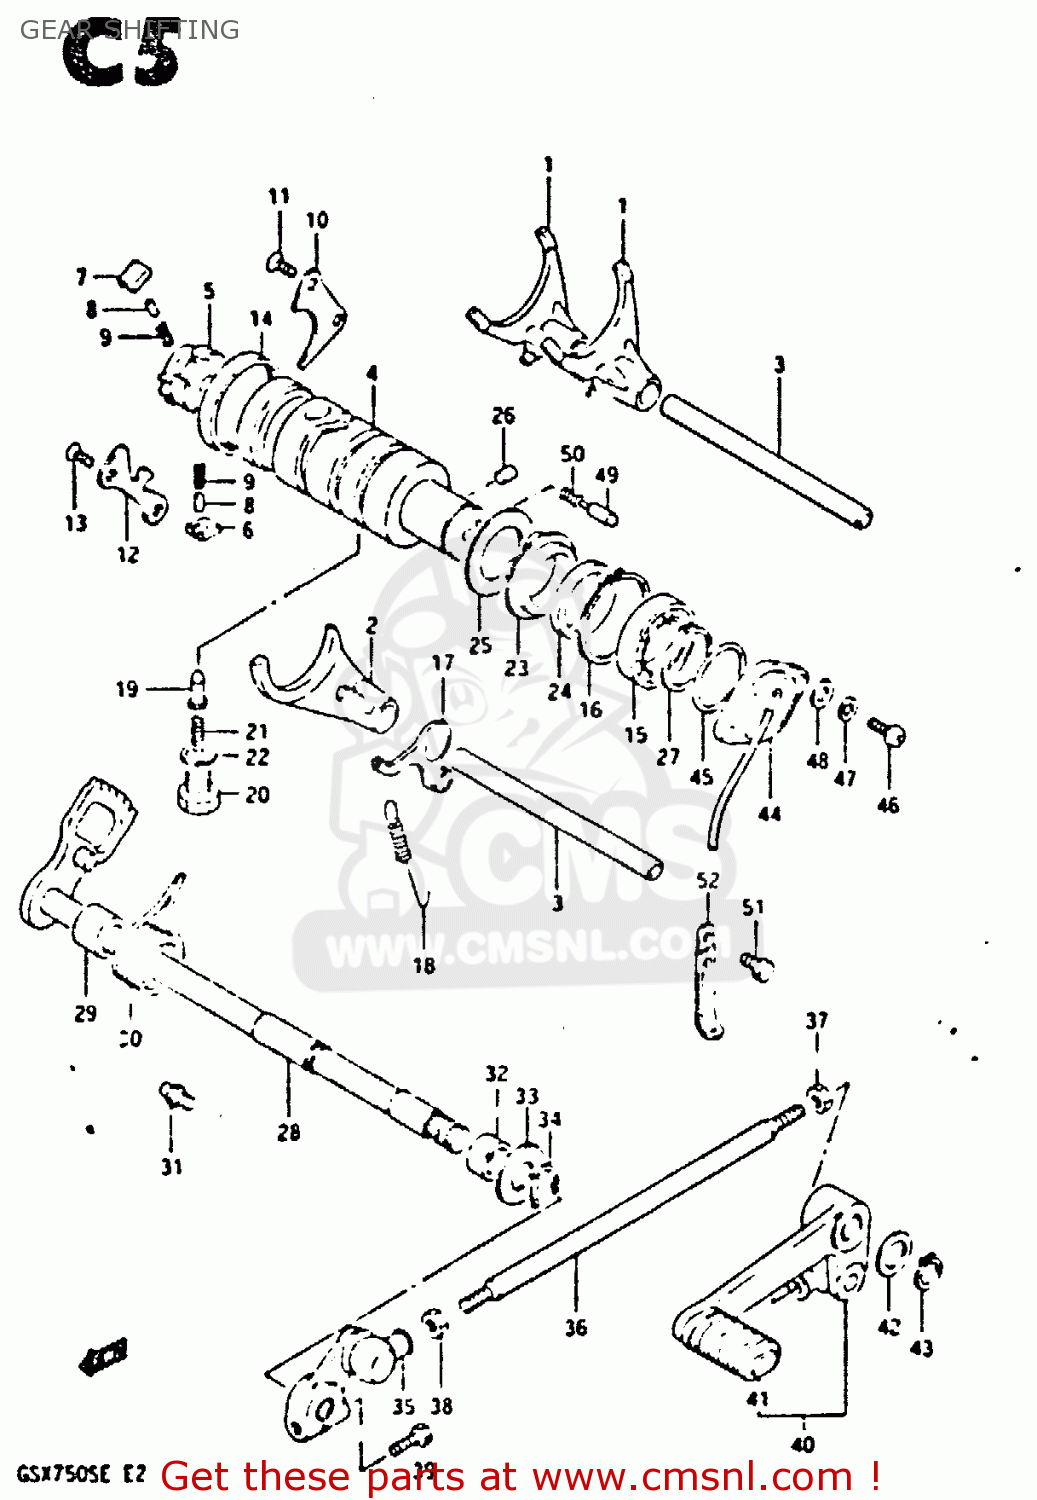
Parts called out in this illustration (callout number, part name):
1	FORK,GEAR SHIFT NO.1
2	FORK,GEAR SHIFT NO.2
3	SHAFT,GEAR SHIFT FORK
4	CAM,GEAR SHIFT
5	GEAR,GEARSHIFT CAM DRIVE
6	PAWL,GEAR SHIFT NO.1
7	PAWL,GEAR SHIFT NO.2
8	PIN(5X8)
9	SPRING
10	LIFTER,GEAR SHIFT PAWL
11	SCREW
12	GUIDE,GEAR SHIFT CAM
13	SCREW
14	BEARING(43X49X12)
15	BALL BEARING
16	CIRCLIP,42MM
17	STOPPER,GEAR SHIFTING
18	SPRING
19	STOPPER,GEAR SHIFTING
20	HOLDER,GEAR SHIFT CAM STOP SPR
21	SPRING
22	GASKET(14X19.2X2) (NAS)
23	PLATE,STOPPER
24	WASHER
25	WASHER,LOCK
26	PIN 4X6
27	CIRCLIP,25MM
28	SHAFT, GEAR SHIFTING
29	SPACER(12X20X15.3)
30	SPRING
31	STOPPER,GEAR SHIFT CAM
32	OIL SEAL
33	WASHER (12.5X27X1.6)
34	SPRING,RETAINER
35	ARM, GEAR SHIFT LINK
36	ROD, GEAR SHIFT LINK
37	NUT
38	NUT
39	BOLT
40	LEVER ASSY, GEAR SHIFTING
41	RUBBER,PEDAL
42	WASHER
43	CIRCLIP
44	TERMINAL BASE,NEUTRAL SWITCH
45	O RING(D:2.4,ID:36.5)
46	SCREW(5X14)
47	LOCK WASHER
48	WASHER
49	PIN(5X15.5)
50	SPRING
51	BOLT
52	CLAMP
